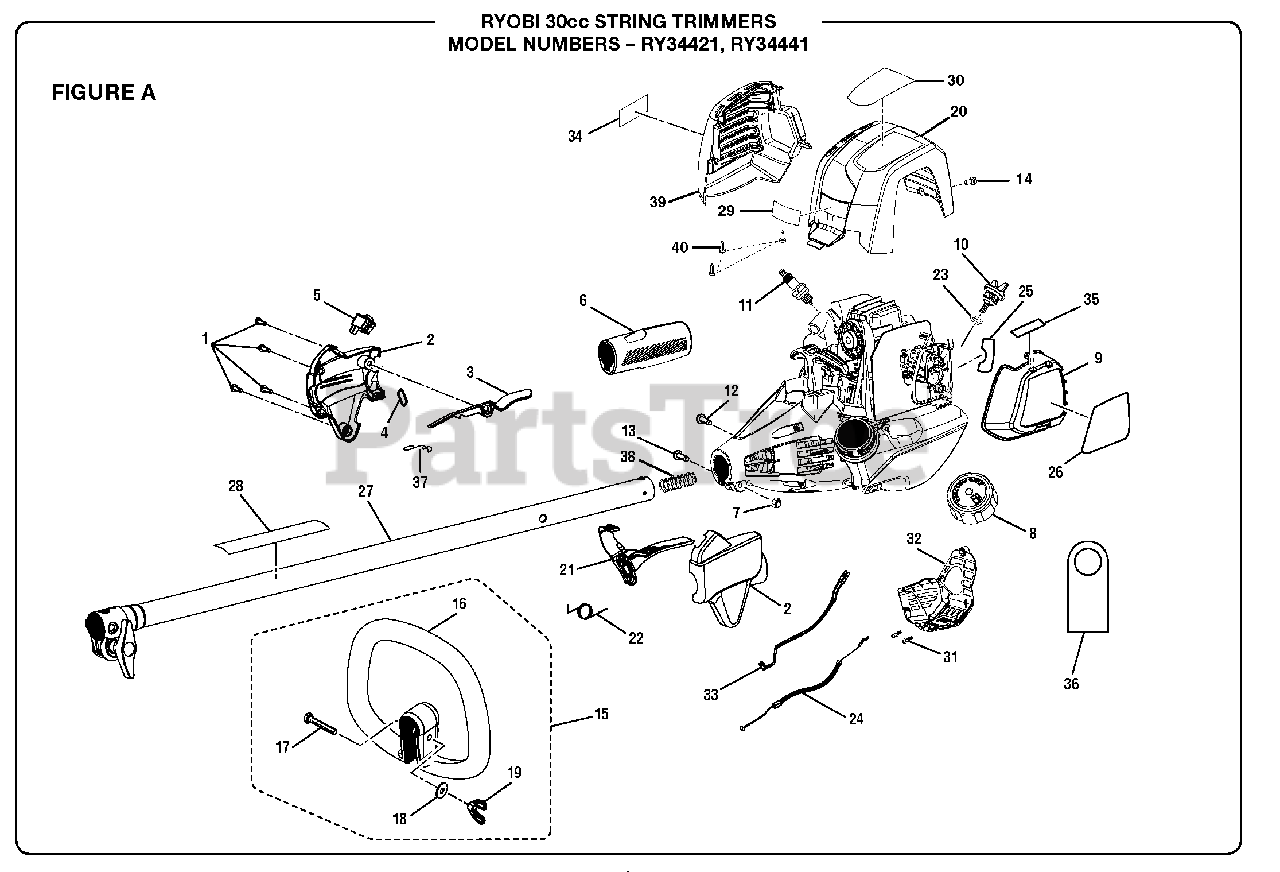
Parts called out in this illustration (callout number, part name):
1	Screw (M4 x 20 mm)
2	Control Handle Assembly
3	Trigger Lock
4	Strap Hanger
5	Switch (Momentary Contact)
6	Rear Handle
7	Hex Nut (M6.3 x 1)
8	Fuel Cap Assembly
9	Air Box Cover
10	Oil Cap/Dipstick
11	Spark Plug (Champion RY4C)
12	Screw (#8-16 x 5/16 in.)
13	Bolt (M6 x 1 x 20 mm)
14	Screw (M5 x 11 mm)
15	Front Handle Assembly
16	Front Handle
17	Bolt (1/4-20 x 40 mm)
18	Washer (1/4 in.)
19	Wing Nut (1/4-20)
20	Top Cover
21	Throttle Trigger
22	Throttle Trigger Spring
24	Throttle Cable
25	Hot Surface Label
26	Starting Label
27	Upper Boom Assembly
28	Warning Label
29	Logo Label
30	C430 Label (RY34421)
30	S430 Label (RY34441)
31	Screw (#6-19 x 1/2 in.)
32	CE Cover (Bottom Cover)
33	Lead Assembly
34	Combustion Warning Label
35	Choke Label
36	Oil Hang Tag
38	Compression Spring
39	Muffler Housing
40	Screw (M4 x 12 mm)
